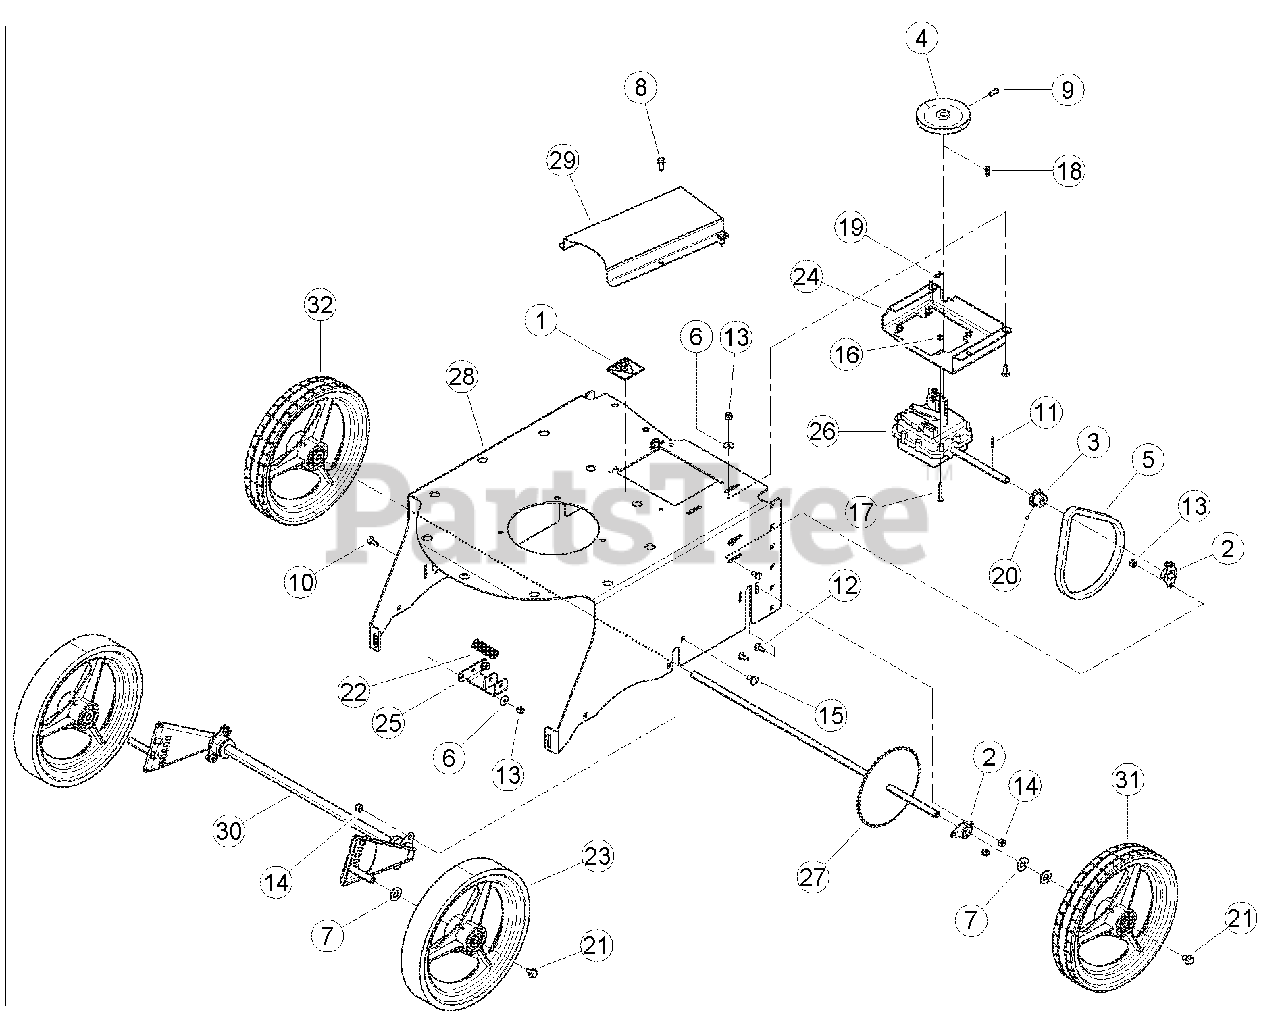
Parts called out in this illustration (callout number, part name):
1	DECAL, SHIELD DANGER
2	BEARING, 1/2 FLANGE
3	SPROCKET, 35 B10
4	PULLEY, 4 O.D. X 12 MM BORE
5	CHAIN, #35 X 62 PITCH W/ CONN. LINK
6	WASHER, 1/4 FLAT
7	WASHER, 1/2 SAE FLAT
8	SCREW, 11/32 X 7/8 HWH AB THREAD
9	SCREW, 1/4 X 5/8 SQ HD SET
10	BOLT, 1/4 X 3/4 CRG
11	PIN, 1/8 X 7/8 SPRING
12	BOLT, 1/4 X 5/8 CRG
13	NUT, 1/4 NYLOCK
14	NUT, 5/16 NYLOCK
15	BOLT, 5/16 X 5/8 CRG
16	NUT, #10 X 24 NYLOCK
17	SCREW, #10 X 24 X 1-1/2 PAN PHP ZP
18	KEY, 4 MM SP X 20 MM
19	WASHER, #6 SAE FLAT
20	SCREW, #8-32 X 3/16 KNR CUP PT
21	BOLT, 5/16-18 X 1/2 GR5 HH SER/FLN
22	SPRING, COMPRESS LC-072J-6
23	WHEEL ASSEMBLY, BEARVAC PUSH
24	WELDMENT, TRANSMISSION MOUNT
25	WELDMENT, BEARVAC HEIGHT ADJ.
27	WELDMENT, SP LONG AXLE
28	SUPPORT, BEARVAC FRAME
29	GUARD, BEARVAC BELT
30	WELDMENT, AXLE PIVOT
31	WHEEL, BEARVAC SP LEFT
32	WHEEL, BEARVAC SP RIGHT
